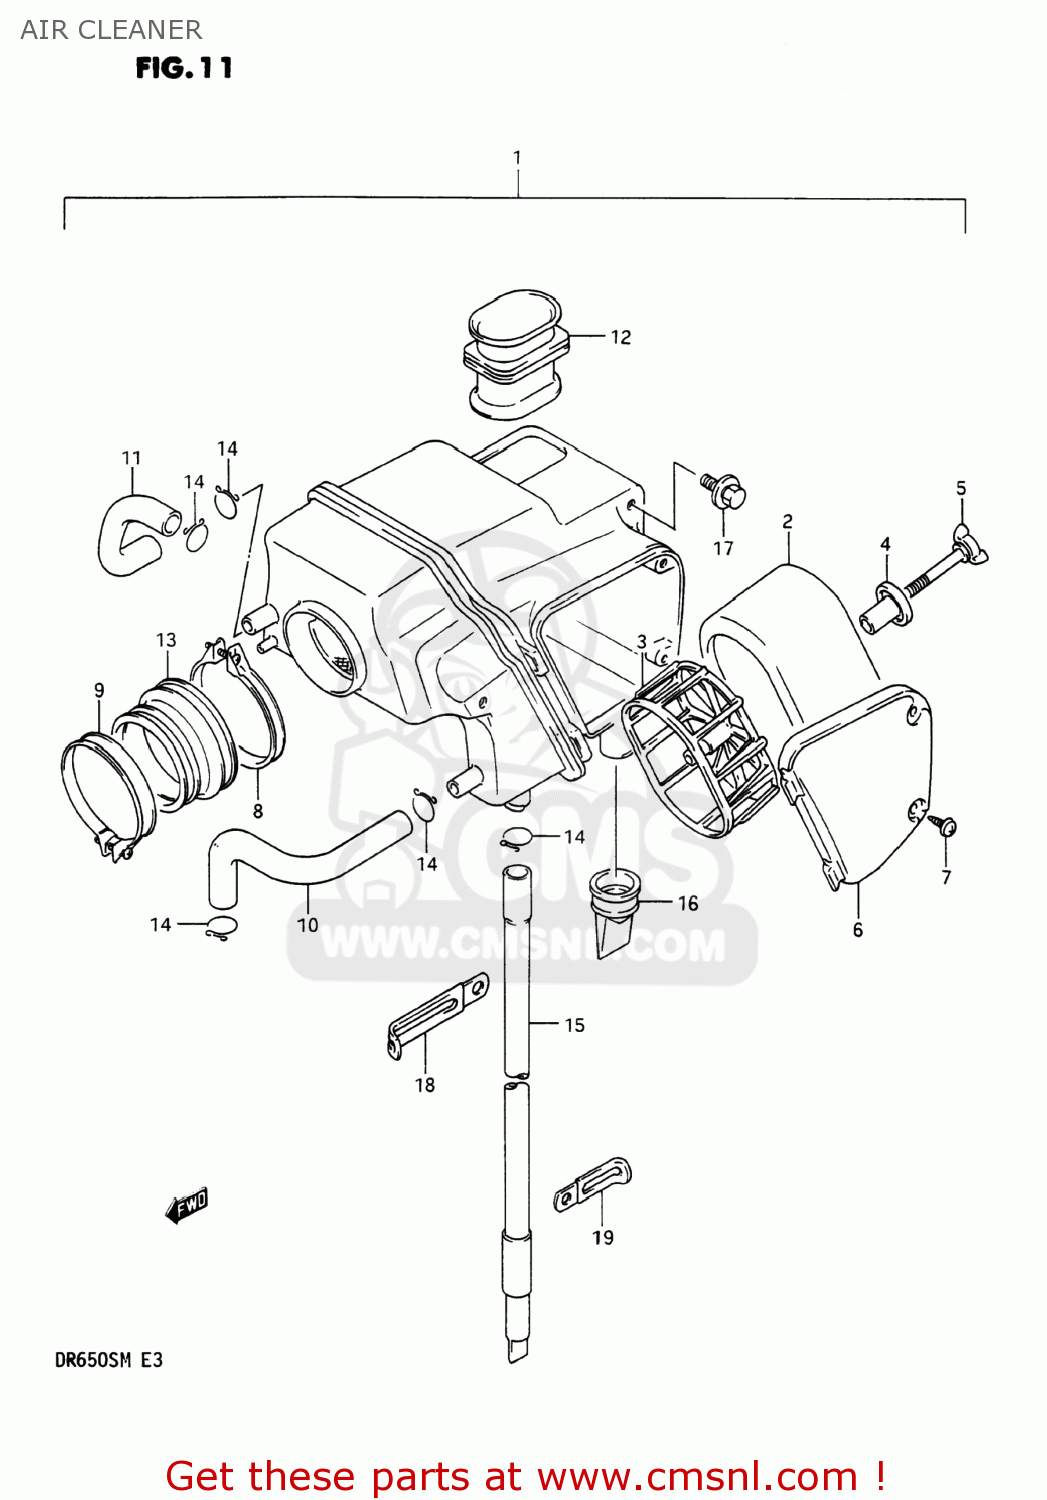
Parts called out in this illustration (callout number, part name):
1	CLEANER ASSEMBLY,AIR
2	FILTER
3	HOLDER,FILTER
4	SPACER
5	BOLT,WING
6	CAP,AIR CLEANER
7	SCREW
8	CLAMP
9	CLAMP
10	TUBE,BREATHER
11	TUBE,CONNECTING
12	TUBE,INLET
13	TUBE,OUTLET
14	CLIP
15	DRAIN TUBE
16	CAP,DRAIN
17	BOLT(6X14)
18	CLAMP
19	CLAMP L:35
